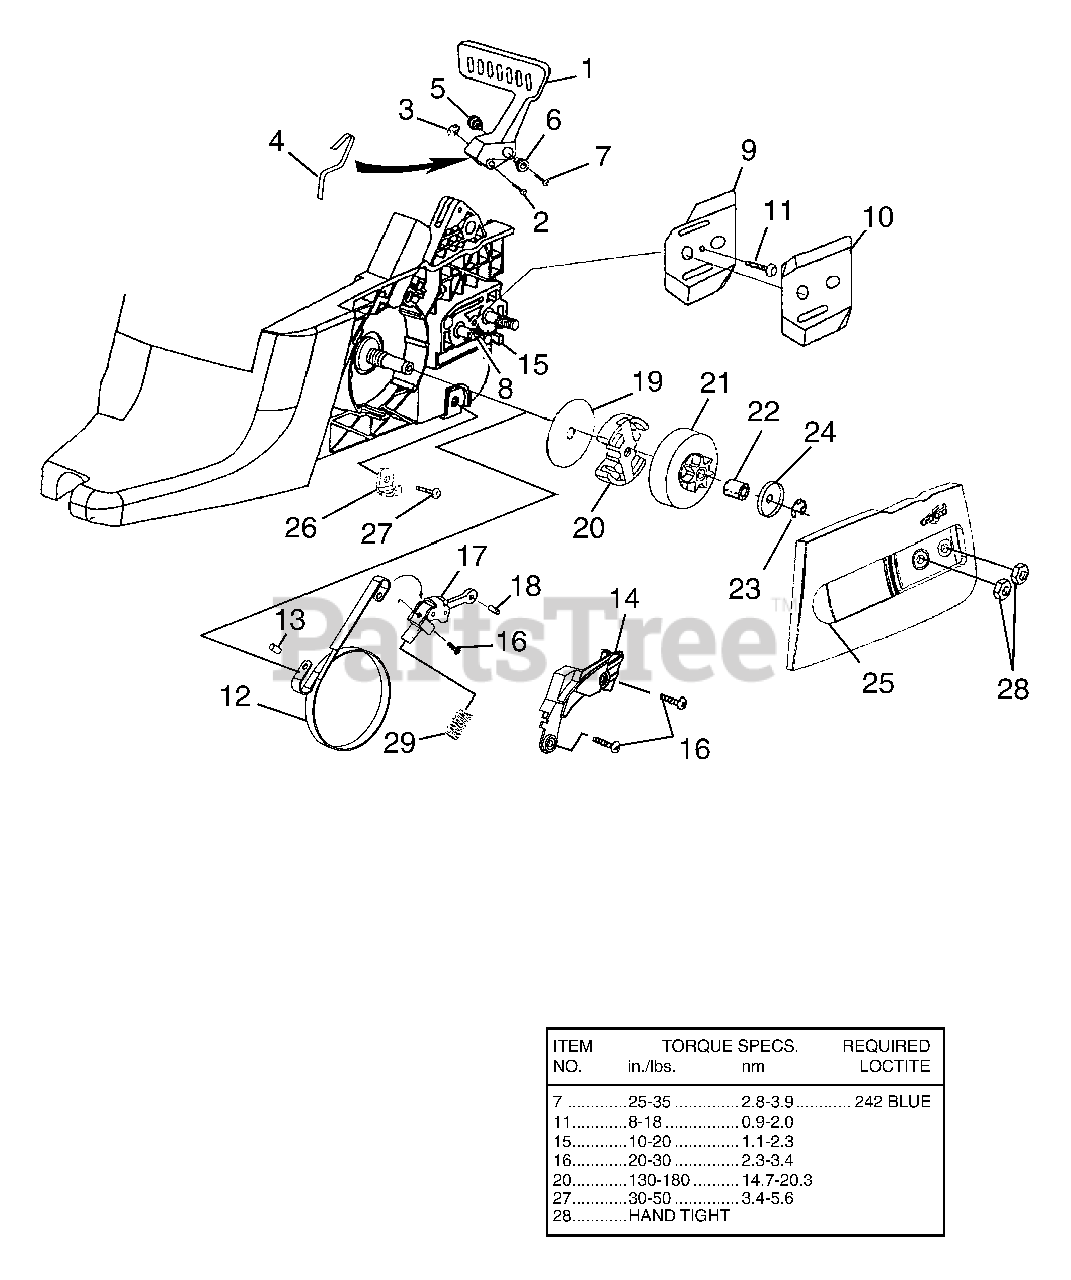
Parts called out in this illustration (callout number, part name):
1	HAND GUARD
2	HAND GUARD ACTUATING PIN
3	RETAINING RING
4	HANDGUARD SPRING
5	PIVOT, L.H.
6	PIVOT, R.H.
7	SCREW (8-32 x 5/8 in.)
8	GUIDE BAR BOLT
9	GUIDE BAR PLATE
10	GUIDE BAR PLATE
11	SCREW (6-19 x 1/2 in.)
12	CHAIN BRAKE BAND
13	ROLL PIN
14	CHAIN BRAKE COVER
15	ADJUSTING PIN KIT
16	SCREW (8-19 x .320)
17	CHAIN BRAKE LINK
18	ROLL PIN
19	THRUST WASHER
20	CLUTCH & HARDWARE
21	DRUM SPROCKET (.375 PITCH)
22	NEEDLE BEARING
23	RETAINING RING
24	CUPPED WASHER
25	DRIVE CASE COVER
26	CHAIN CATCHER
27	SCREW (10-24 x 1/2 in.)
28	HEX NUT
29	COMPRESSION SPRING
